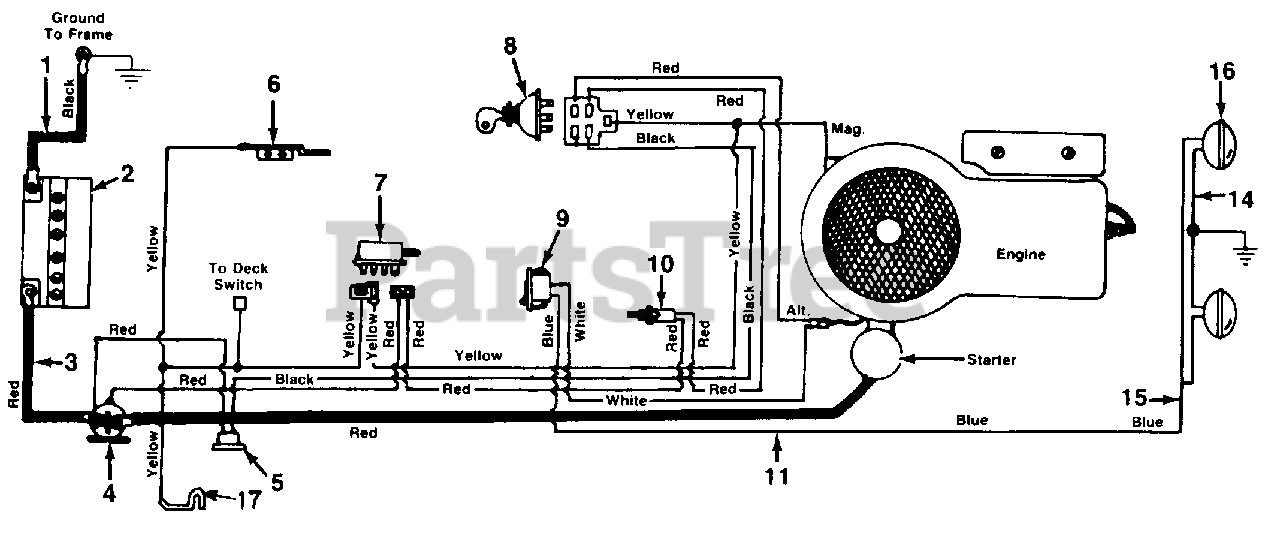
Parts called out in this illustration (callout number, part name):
1	Ground Wire
2	Battery
3	Electric Wire
4	Solenoid
5	Circuit Breaker
6	Spring Switch
7	Safety Switch
8	Key Switch
9	Light Switch
10	Safety Switch (Black)
11	Harness
14	Ground Wire
15	Headlight Harness
16	Lamp
